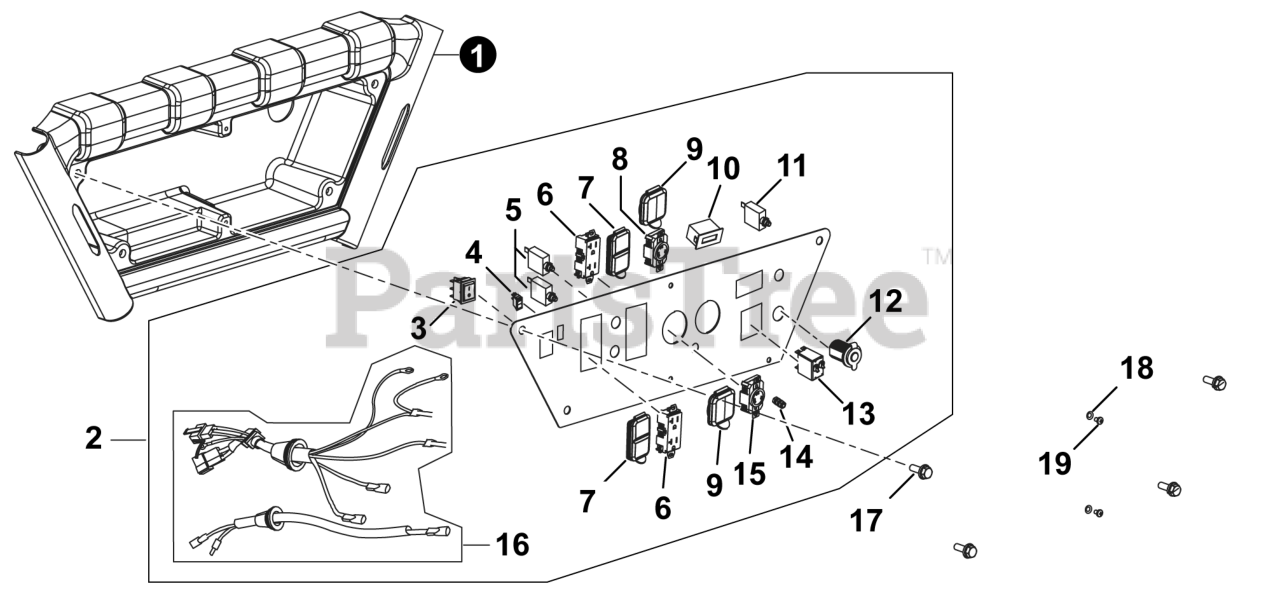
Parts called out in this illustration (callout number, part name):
1	SEAT, PANEL
2	PANEL, CONTROL
3	SWITCH SUBASSEMBLY
4	SWITCH SUBASSEMBLY
5	BREAKER, AC
6	SOCKET, 120V POWER
7	COVER, SOCKET
8	SOCKET, 240V TWISTLOCK
9	COVER, TWISTLOCK
10	DISPLAY, DIGITAL
11	PROTECTOR, OVERCURRENT
12	SOCKET SUBASSEMBLY, D.C
13	BREAKER, DOUBLE-POLE
14	TERMINAL, GROUND BOLT
15	SOCKET, 120V TWISTLOCK
16	HARNESS SET, WIRING
18	WASHER, FLAT
